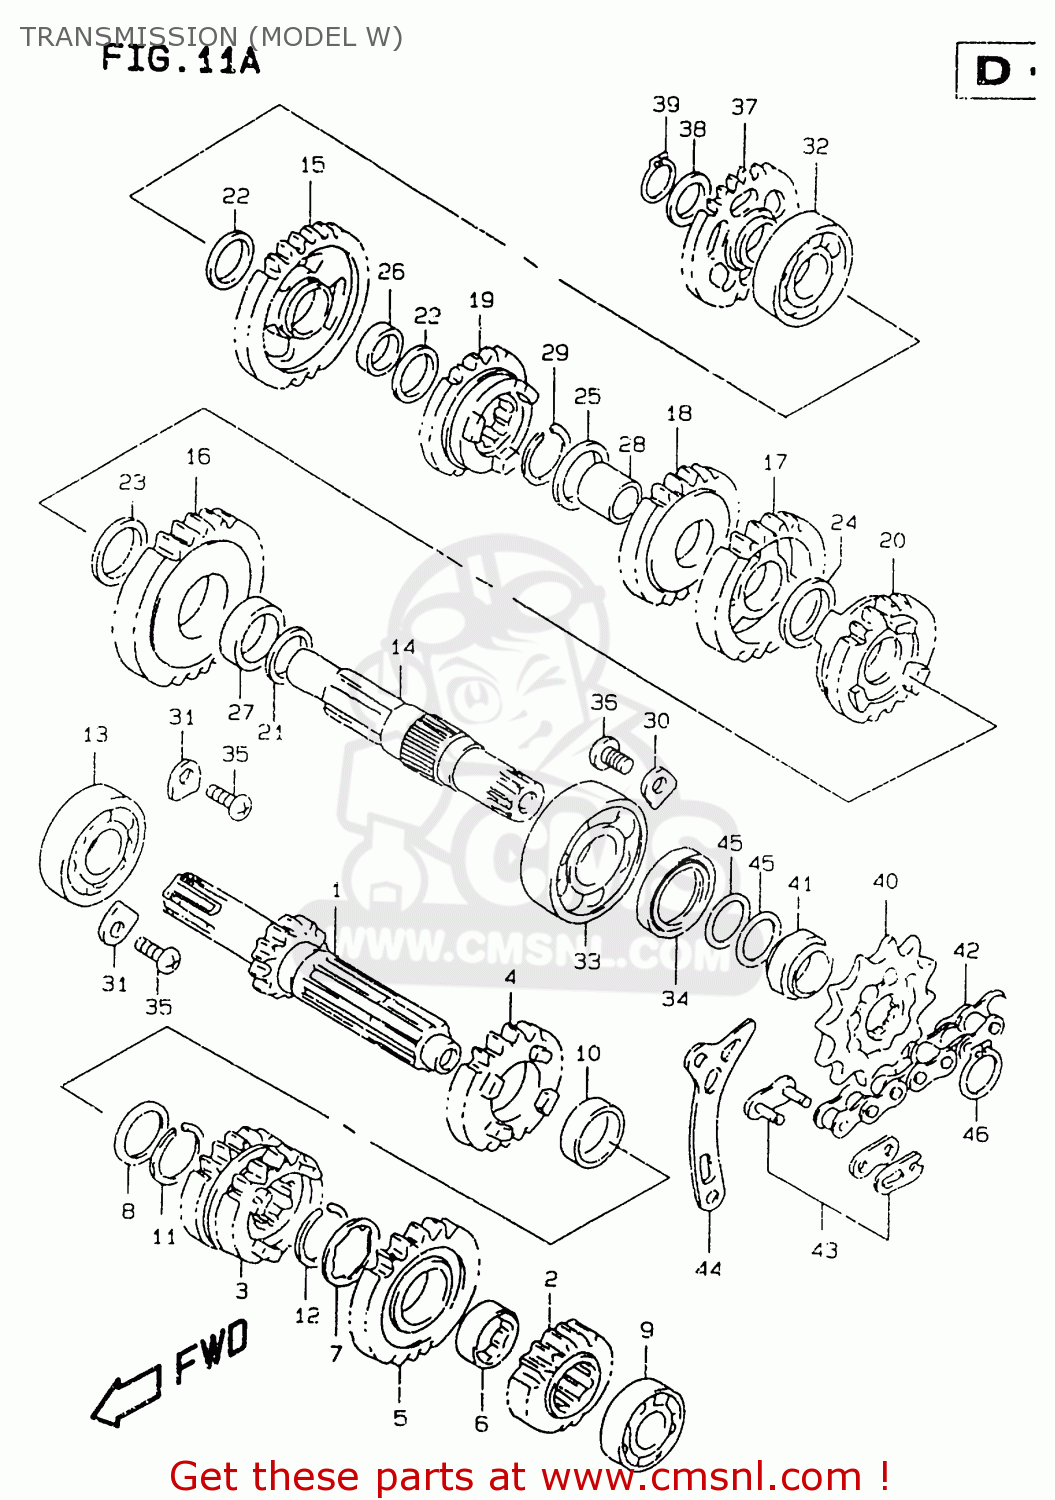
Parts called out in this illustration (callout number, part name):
1	SHAFT,COUNTER(NT:14)
2	GEAR,2ND DRIVE(NT:16)
3	GEAR,THIRD & FOURTH DRIVE,N
4	GEAR,FIFTH DRIVE (NT:19)
5	GEAR,SIXTH DRIVE (NT:20)
6	BUSH,6TH DRIVE GEAR
7	WASHER,LOCK
8	SHIM(22X28X1)
9	BEARING(20X47X12)
10	BUSH(22X26X9)
11	CIRCLIP
12	CIRCLIP
13	BEARING
14	SHAFT,DRIVE
15	GEAR,1ST DRIVEN(NT:30)
16	GEAR,2ND DRIVEN(NT:28)
17	GEAR,THIRD DRIVEN (NT:26)
18	GEAR,4TH DRIVEN(NT:24)
19	GEAR,5TH DRIVEN(NT:20)
20	GEAR,SIXTH DRIVEN (NT:19)
21	WASHER(20X30X3)
22	SHIM(17X26X1)
23	SHIM(22X30X1)
24	SHIM(22X30X1)
25	SHIM(22X30X1)
26	BUSH(17X20X9)
27	BUSH(22X26X9)
28	BUSH(22X25X18)
29	CIRCLIP
30	RETAINER,COUNTER BEARING,R
31	RETAINER
32	BEARING(17X40X9.5)
33	BEARING(20X52X12.5)
34	SEAL,OIL(28X38X6)
35	SCREW
36	SCREW
37	GEAR,KICK STARTER IDLE
38	SHIM(17X24X0.5)
39	CIRCLIP,17MM
40	SPROCKET,ENGINE
41	SPACER,ENGINE SPROCKET
42	CHAIN ASSEMBLY DID520DM.11
43	JOINT SET,CHAIN
44	PLATE,FR CHAIN GUIDE
45	O RING(D:1.9,ID:19.8)
46	CIRCLIP
